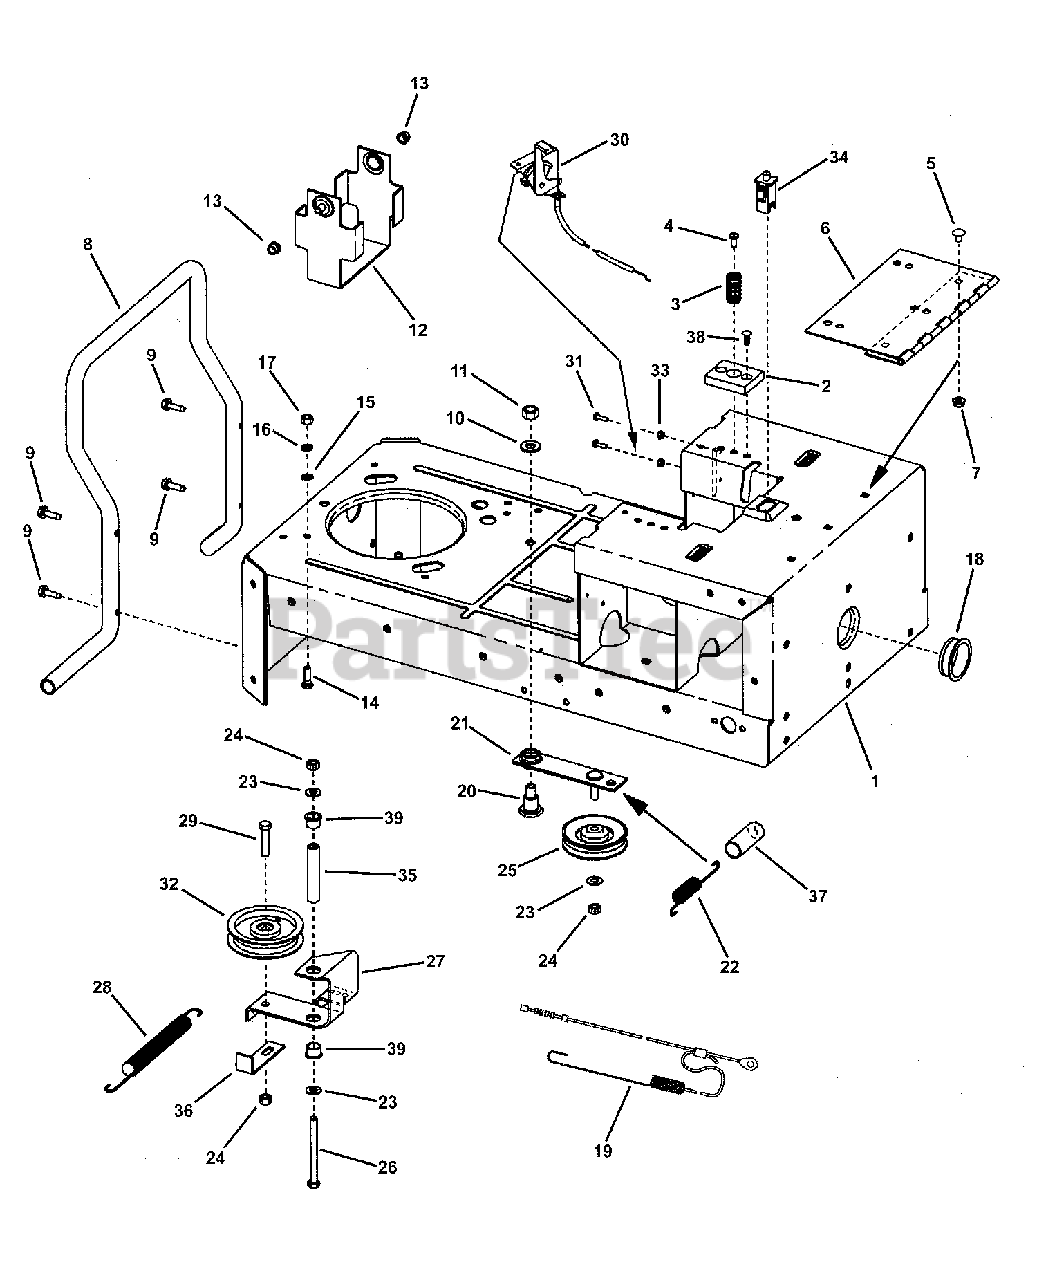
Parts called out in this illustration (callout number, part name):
1	WELDMENT, Rear Frame
2	CUSHION, Seat Support
3	SPRING, Seat Support
4	SCREW, 1/4-20 x 5/8" Pan Head Self-Tap (Torx)
5	BOLT, 5/16-18 x 1/2" Short Neck Carriage, GR5
6	HINGE, Seat
7	NUT, 5/16-18 Hex Flange Lock, GR5
8	BUMPER, Rear
9	SCREW, 5/16-18 x 1-1/2" Hex Washer Self-Tap
10	WASHER, .531 x 1.062 x .121 SAE Flat
11	NUT, 1/2-13 Hex Center Lock, GR5 or B
12	WELDMENT, Battery Bracket
13	BUSHING, Tie Rod
14	SCREW, 5/16-24 x 1" Hex Head Cap, GR5
15	RETAINER, 5/16" Bolt
16	WASHER, .32 x .58 x .08 Split Lock
17	NUT, 5/16-24 Hex, GR5 or B
18	GROMMET
19	ASSEMBLY, Brake/Clutch Cable
20	BOLT, 1/2-13 Hex Shoulder
21	WELDMENT, Idler Arm, Primary
22	SPRING, Extension- 5" long
23	WASHER, 3/8" SAE Flat
24	NUT, 3/8-16 Hex Center Lock, GR5 or B
25	PULLEY,Idler, V 3.30 HA
26	BOLT, 3/8-16 x 4" Hex Head Cap, GR5
27	BRACKET, Hydro Idler
28	SPRING, Extension, Hydro Idler
29	SCREW, 3/8-16 x 1-3/4" Hex Head Cap, GR5
30	CABLE, Hydro Release Valve
31	SCREW, #10-32 x 5/8" Hex Washer Head Machine
32	IDLER, 4.12" Outside Diameter, Flat
33	NUT, #10-32 Hex Nyloc
34	SWITCH, Seat (NO/NC) Snap-In
35	SLEEVE, Idler
36	GUIDE, Belt
37	COVER-Spring
38	FASTENER, Ratchet
39	BUSHING, Flange, .64 x .75 x .5
